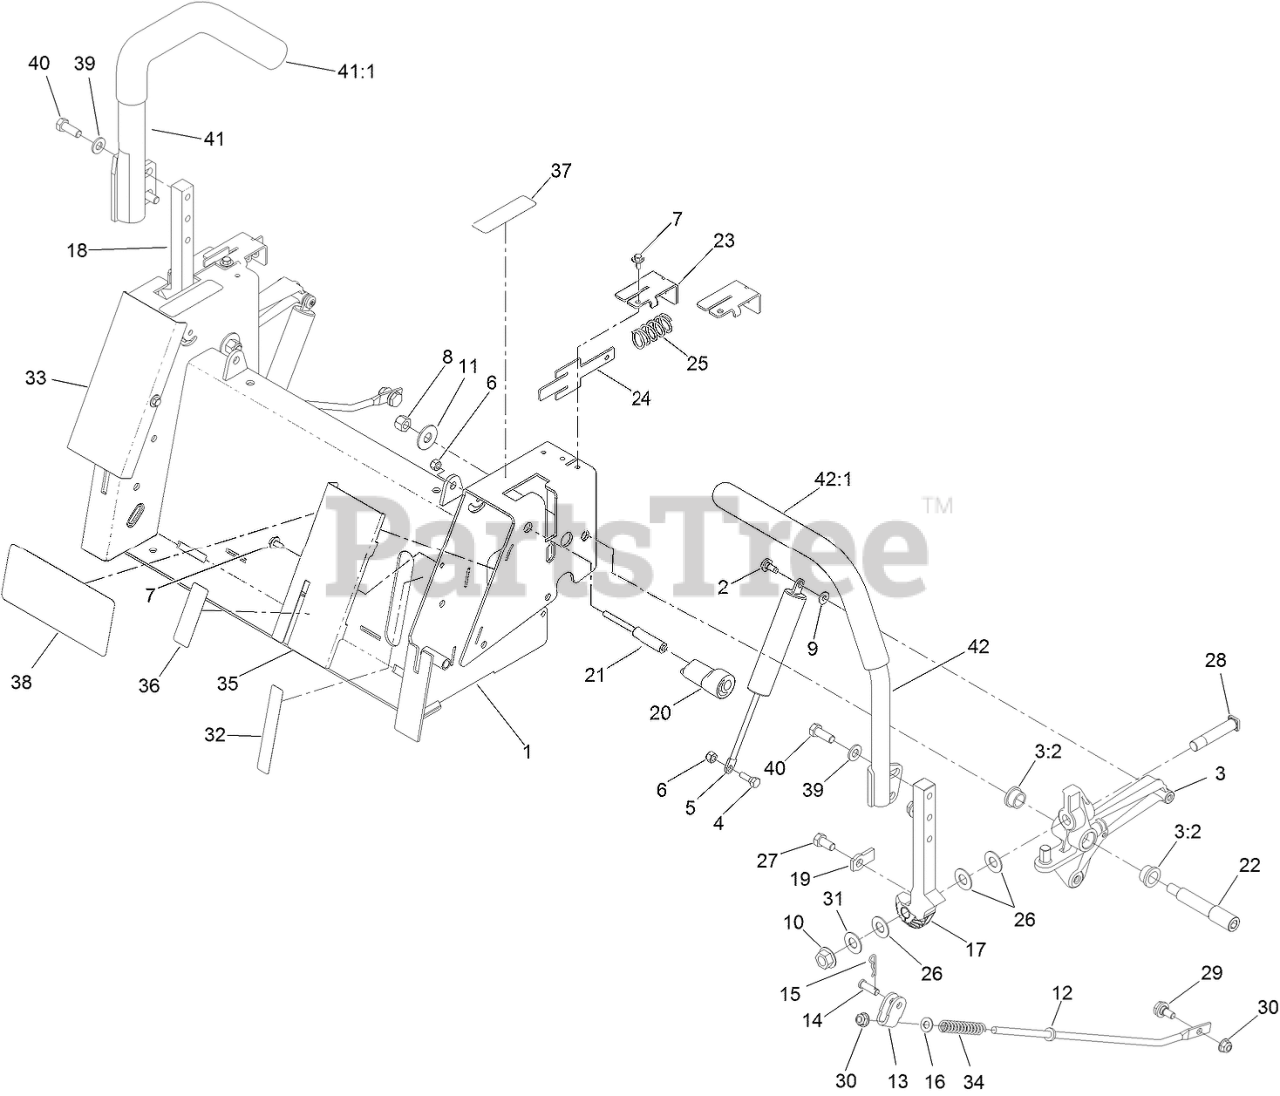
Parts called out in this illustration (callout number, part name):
1	BOX-CONTROL
2	SCREW-SHOULDER
3	ACTIVATOR ARM ASM
3:2	BUSHING
4	BOLT-SHOULDER
5	DAMPER
6	NUT-LOCK, NI
7	SCREW-HHFTF
8	NUT-LOCK, NI
9	WASHER
10	NUT-HF
11	WASHER-FLAT
12	ROD-CONTROL
13	BRACKET-CONTROL
14	PIN-CLEVIS
15	PIN-COTTER
16	WASHER-PLAIN
17	ARM-ACTUATOR, LH
18	ARM-ACTUATOR, RH
19	TAB-STOP
20	ECCENTRIC
21	SCREW-ECCENTRIC
22	BOLT-SHOULDER
23	BRACKET-RETURN
24	PLATE-RETURN
25	SPRING-COMPRESSION
26	WASHER-PIVOT
27	SCREW-HH
28	BOLT-SHOULDER
29	BOLT-SHOULDER
30	NUT-HF, NI
31	WASHER-TEFLON
32	DECAL-FILL, FUEL
33	COVER-CONTROL, RH
34	SPRING-RETURN, NEUTRAL
35	COVER-CONTROL, LH
36	DECAL-BRAKE, PARKING
37	DECAL-CONTROL, MOTION
39	WASHER-FLAT
40	SCREW-HH
41	RH LEVER/GRIP ASM
41:1	Grip-Control, Motion
42	LH LEVER/GRIP ASM
42:1	Grip-Control, Motion
